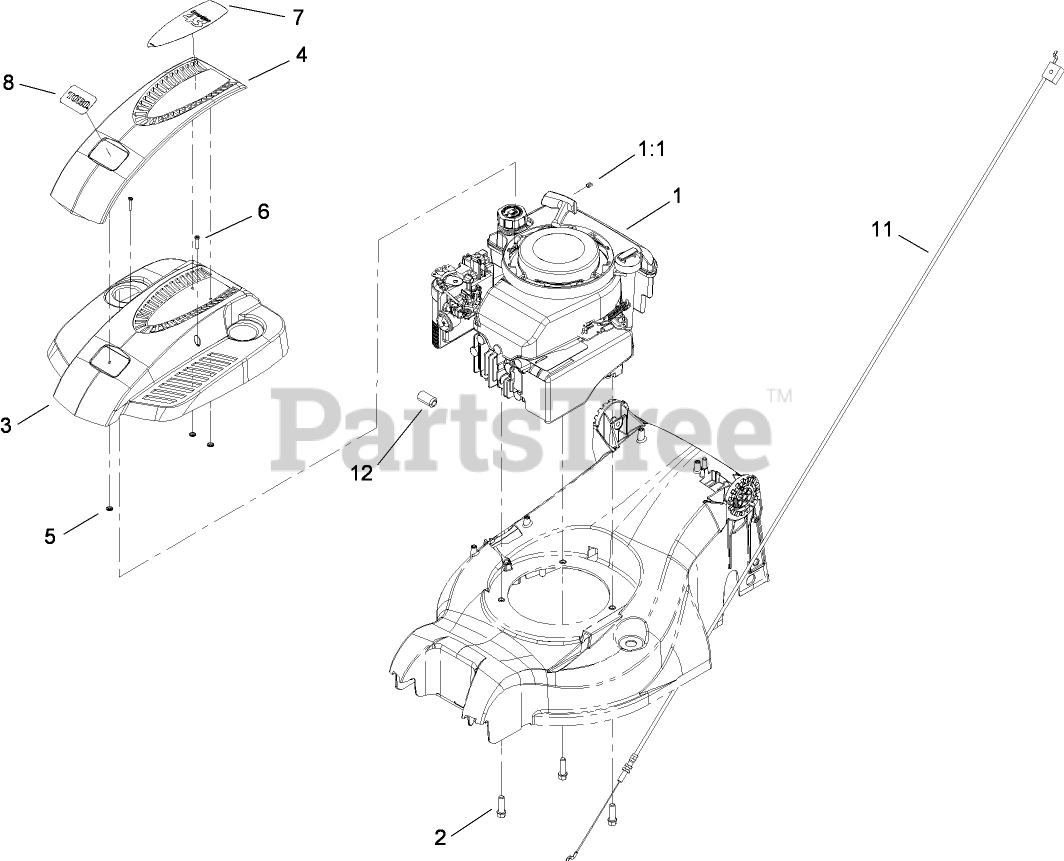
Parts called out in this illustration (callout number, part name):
1	Loose Parts Package
1:1	STOP-ROPE
2	SCREW-TAPTITE
3	SHROUD-ENGINE
4	COVER-SHROUD
5	CLIP-PUSH
6	SCREW-PPH
12	FERRITE-SNAP ON
